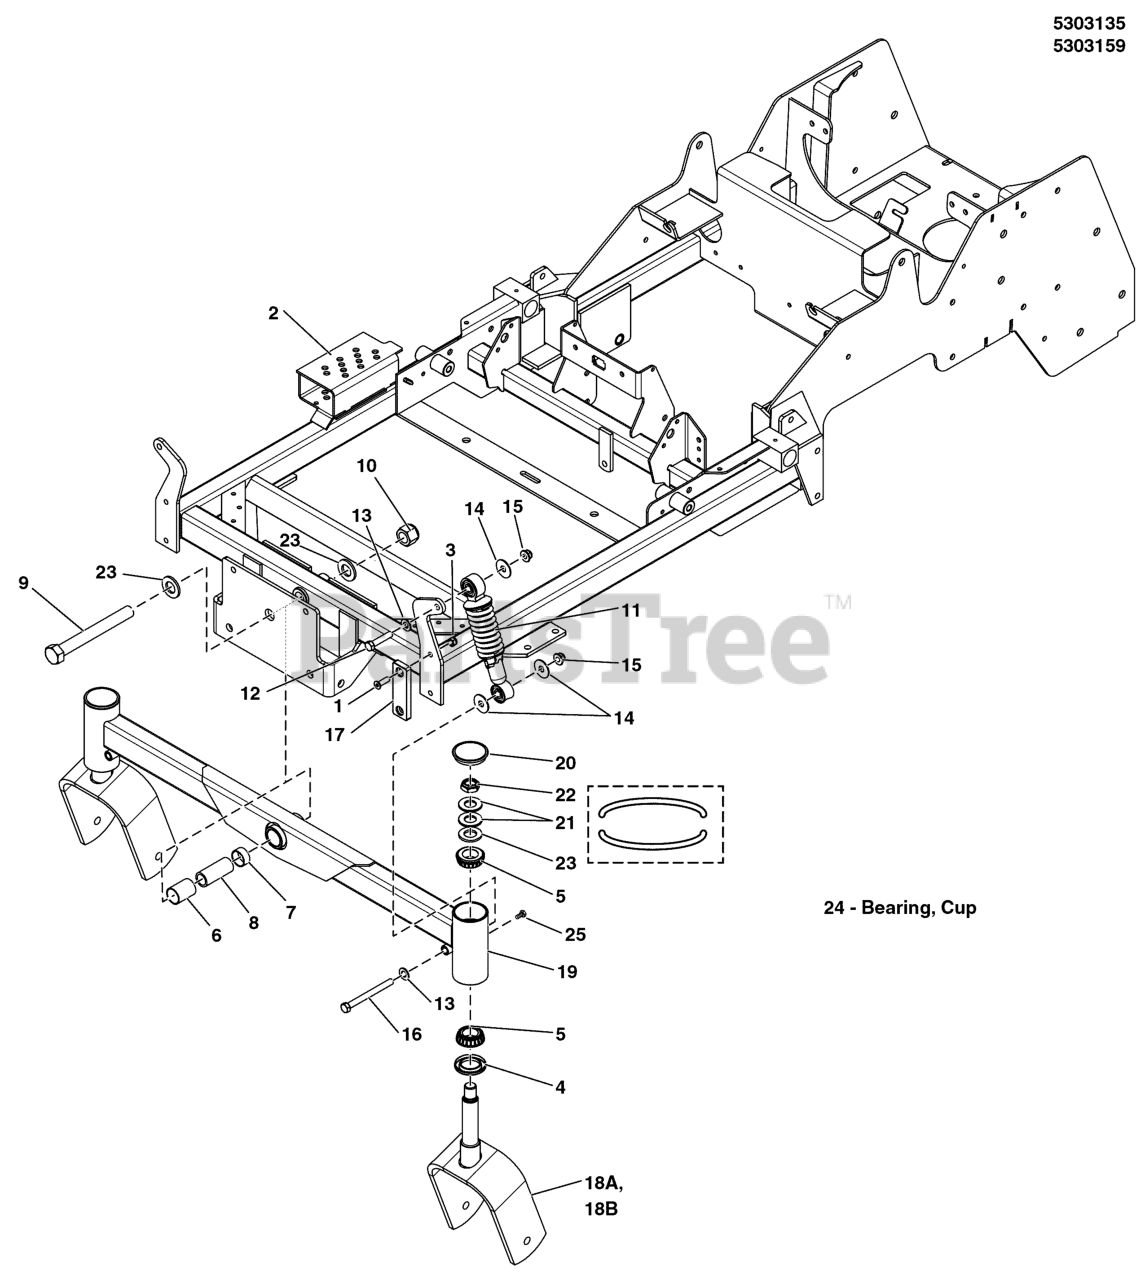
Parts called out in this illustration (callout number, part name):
1	SCREW, 5/16-18 X 1 PHILLIPS HD, BZ
2	* WELD, MAIN FRAME, IS600Z - RED
3	NUT, 5/16-18 HEX NYLON LOCK
4	SEAL, GREASE
5	BEARING, TAPERED ROLLER, 1
6	PIVOT BEARING-1.00 X 1.125 ODX1.50
7	PIVOT BEARING, 1.00 X 1.125 OD X .50
8	SPACER, .75 X 1.00 X 2.38
9	BOLT, 3/4-16 X 6-1/2 YZ GD8
10	NUT, 3/4-16 HEX NYLON LOCK
11	SHOCK, SPRING ASSEMBLY
12	BOLT, 3/8-16 X 1-3/4" GD5 CZ
13	WASHER, 3/8 SAE
14	WASHER-3/8 FENDER
15	NUT, 3/8-16 HEX NYLOCK FLANGE
16	BOLT, 3/8-16 X 4" GD5 CZ
17	PAD, FRICTION - 1.25 X 4.00
18A	WELD, CASTER YOKE - RED
18B	WELD, CASTER YOKE - RED
19	WELD, FRONT PIVOT, IS500Z - RED
20	CAP, GREASE, LOW PROFILE
21	WASHER, BELLEVILLE - 1.500 X .755
22	NUT, 3/4-16, HEX JAM NYLON LOCK
23	WASHER, 3/4 SAE
24	BEARING, CUP
25	BOLT, 1/4-28 X 1/2, GD5 YZ
